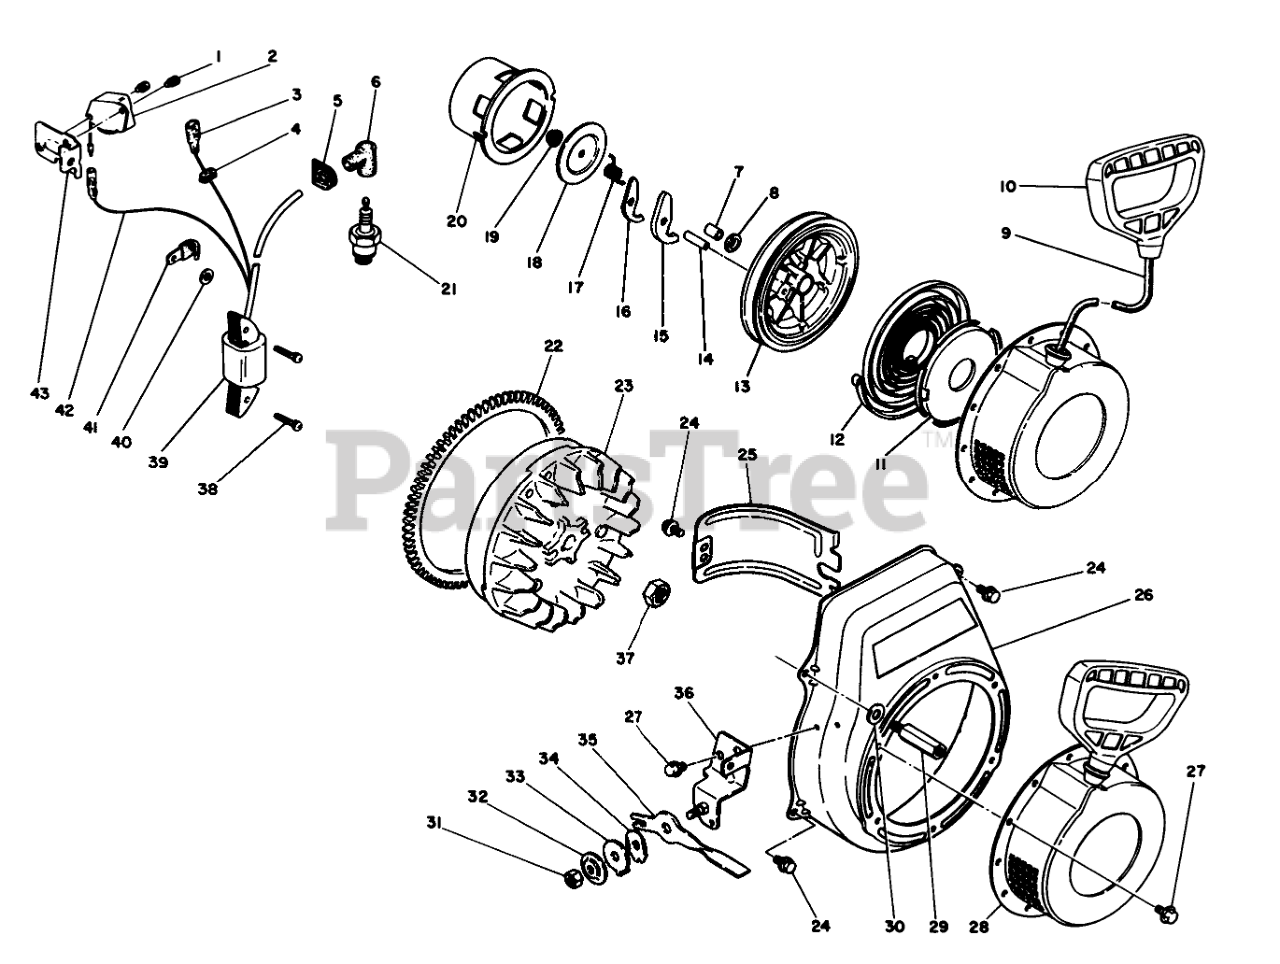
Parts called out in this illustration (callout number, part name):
1	Screw & Washer
2	Bracket-Unit
3	Wire-Leas
4	Grommet
5	GROMMET
7	SHAFT
8	WASHER
12	SPRING
15	RATCHET
16	RATCHET
17	SPRING
18	FRICTION PLATE
20	STARTER PULLEY
21	SPARK PLUG
22	RING GEAR
23	FLYWHEEL
25	CYLINDER BAFFLE
26	FAN COVER
28	Recoil Starter Assembly (Incl. Ref. #7-20)
30	Washer
32	WASHER
33	WASHER
34	LEAF SPRING
35	LEVER
36	BRACKET
38	SCREW & WASHER
39	Coil-Ignition (Incl. Ref. #3, 4 & 42)
41	CLAMP
42	Wire-Lead
43	BRACKET
